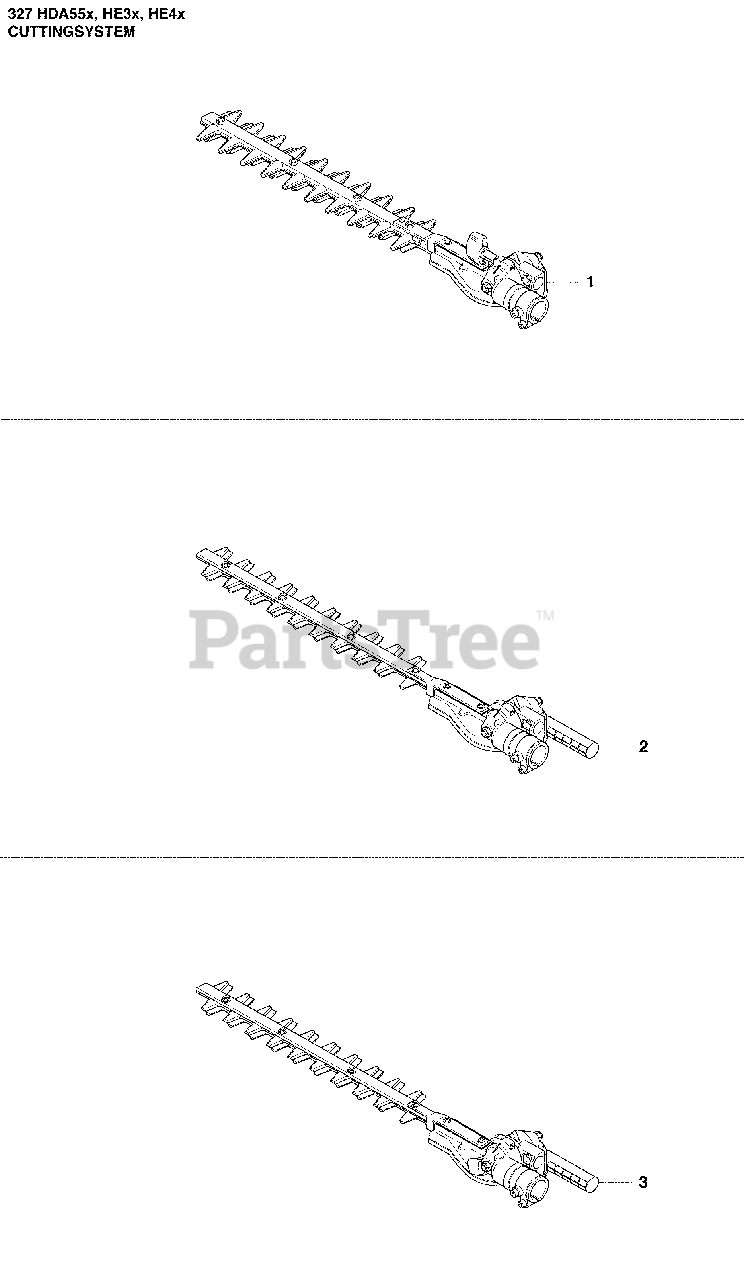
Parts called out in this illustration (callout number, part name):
1	CUTTING DECK KIT
2	CUTTING DECK KIT
3	CUTTING DECK KIT
